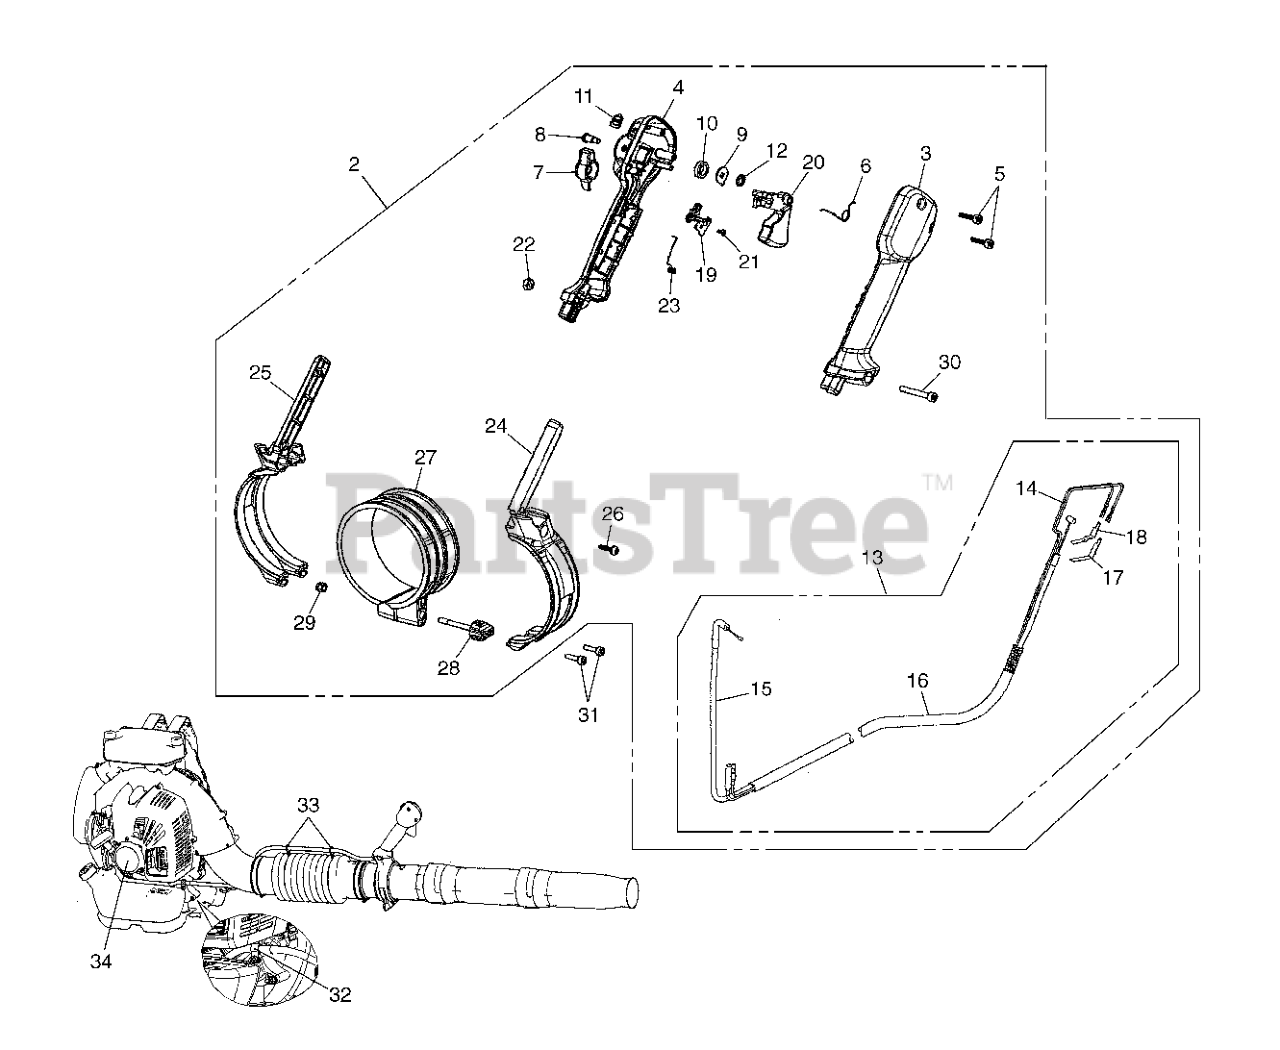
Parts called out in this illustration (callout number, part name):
2	LEVER ASSY
3	HANDLE HALF, RIGHT
4	HANDLE HALF, LEFT
5	SCREW
8	SHAFT PIVOT
10	SPRING
13	WIRING ASSY
14	CORD COMPLETE
15	CABLE, COMP
17	CONTACT SPRING
18	CONTACT SPRING
19	RETAINER
20	SPRING
24	HANDLE HOLDER, RIGHT
25	HANDLE HOLDER, LEFT
34	RECOIL LABEL
